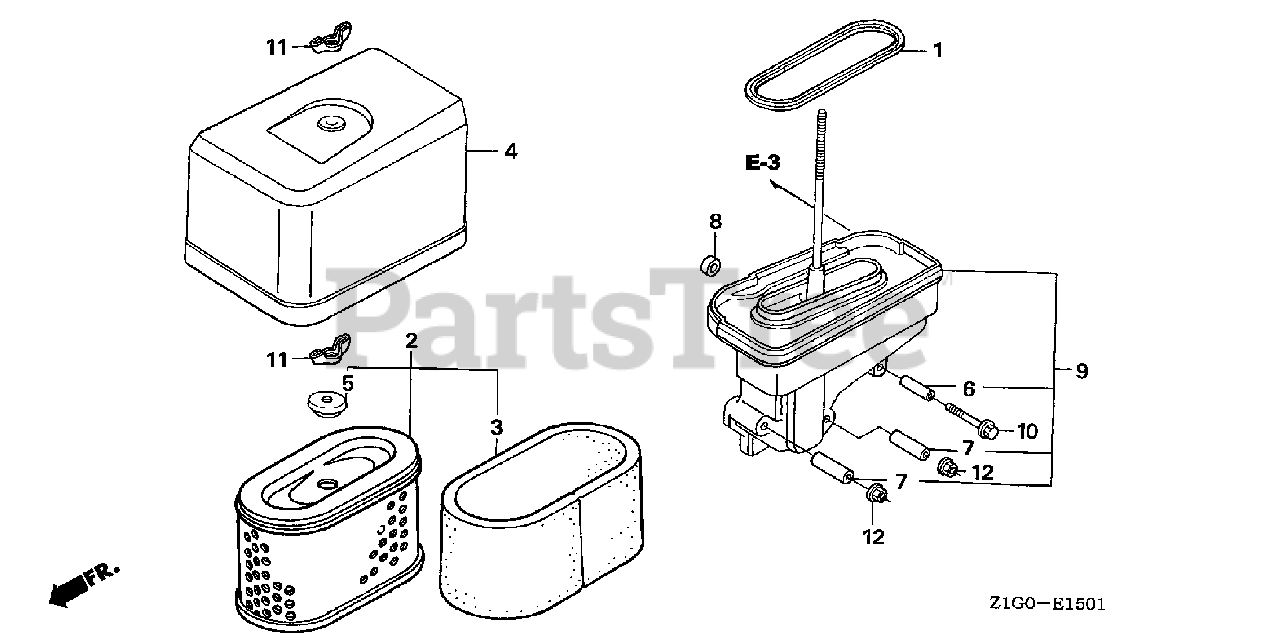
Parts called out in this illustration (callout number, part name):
1	GASKET, ELBOW
2	ELEMENT, AIR CLEANER (METAL BASE)
3	FILTER (OUTER)
4	COVER, AIR CLEANER (DUAL)
5	GROMMET, AIR CLEANER
6	COLLAR, AIR CLEANER
7	COLLAR, AIR CLEANER
8	SPACER, AIR CLEANER ELBOW
9	ELBOW, AIR CLEANER
10	BOLT, FLANGE (6X35) (CT200)
11	NUT, TOOL BOX SETTING
12	NUT, FLANGE (6MM)
